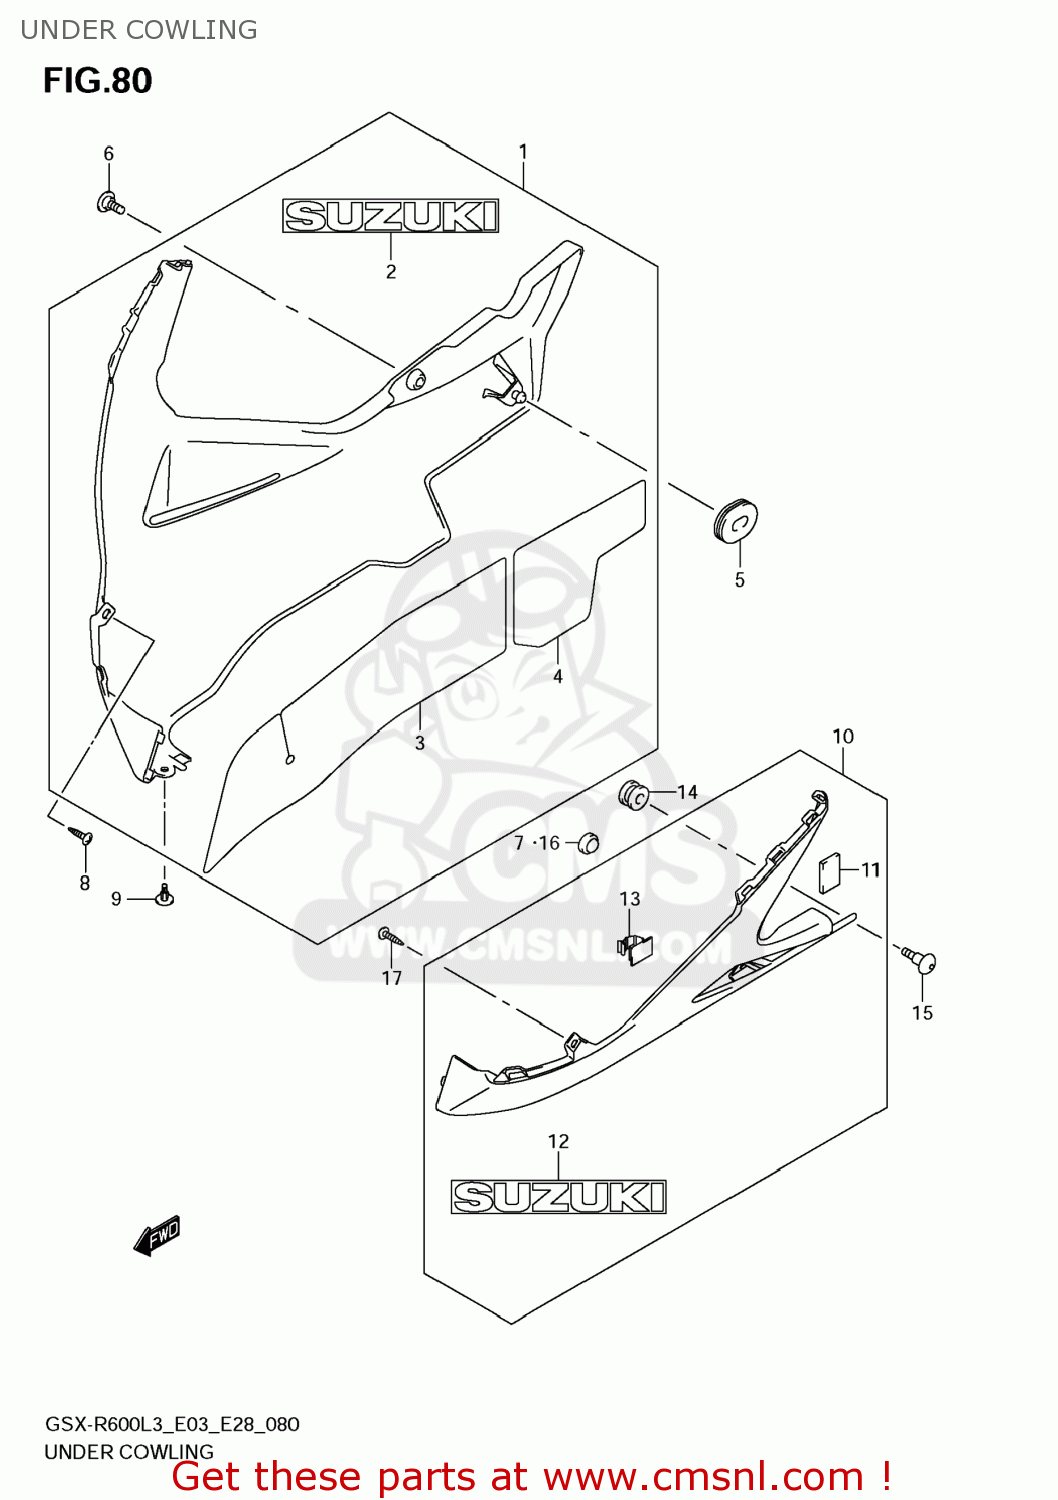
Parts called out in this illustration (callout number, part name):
1	COWLING,UNDER,R(RED)
2	EMBLEM,SUZUKI
3	SHIELD,UNDER COWL HEAT,R
4	SHIELD,UNDER COWL HEAT,R
5	CUSHION,UNDER COWLING,R
6	SCREW,UNDER COWL,R
7	CUSHION
8	SCREW
9	CLIP
10	COWLING,UNDER,L(RED)
11	CUSHION,BRACKET NO.1
12	EMBLEM,SUZUKI
13	CLAMP
14	CUSHION
15	BOLT(6X20)
16	CUSHION
17	SCREW
